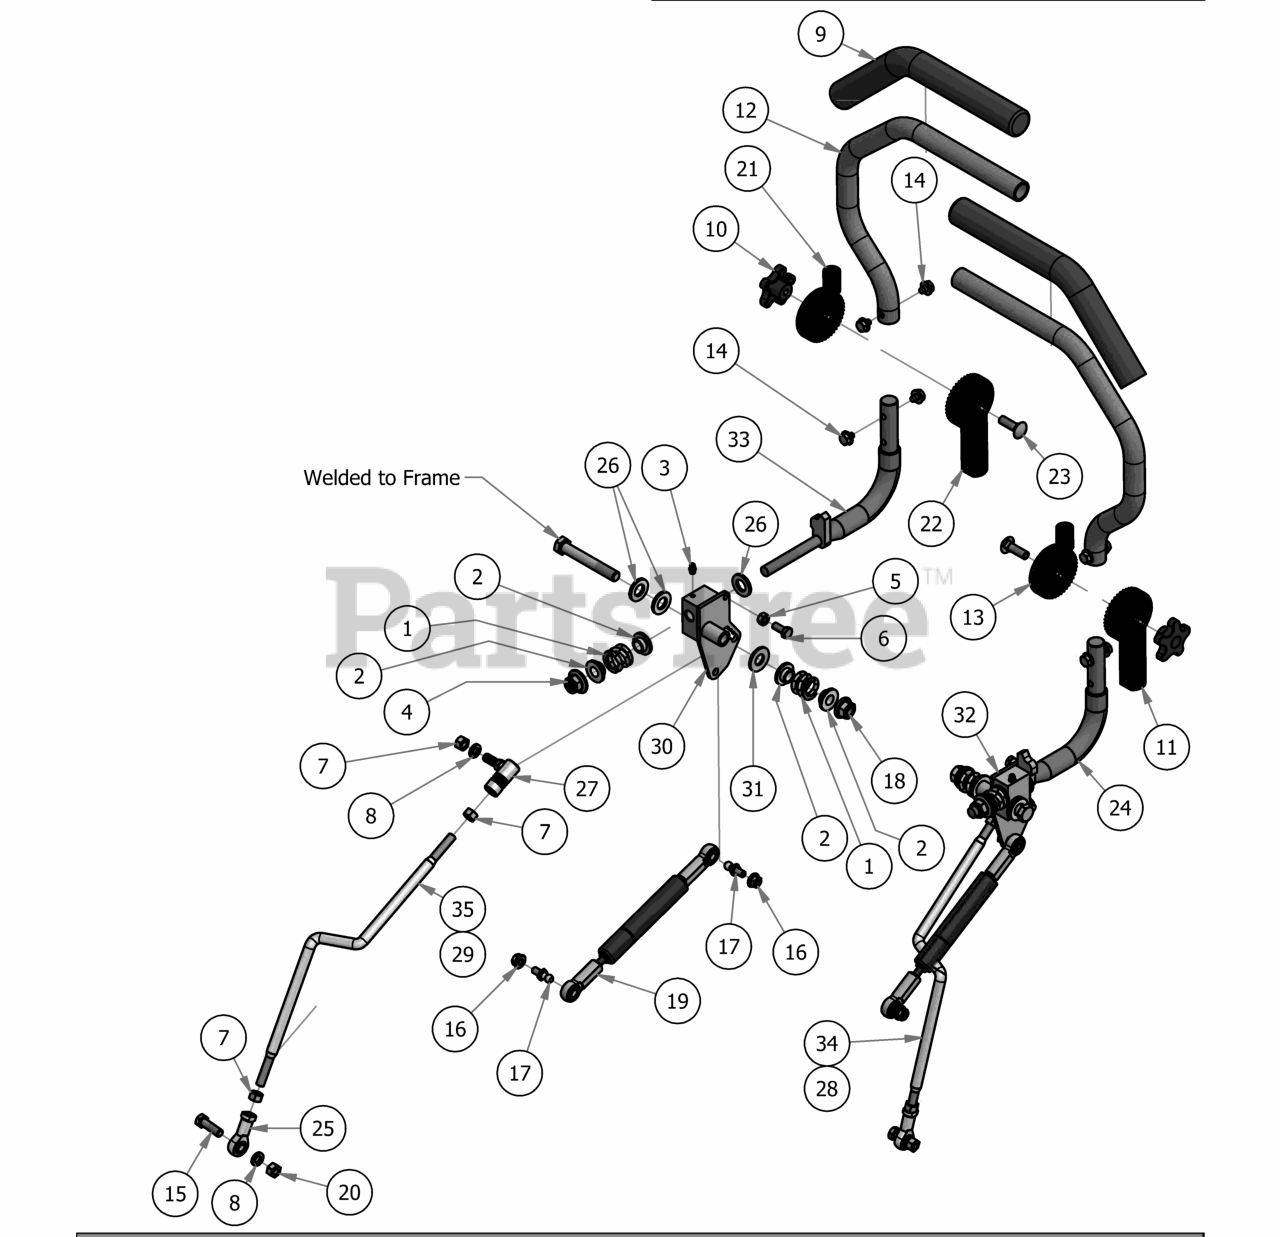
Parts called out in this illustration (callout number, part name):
1	Drive Lever Spring
2	.515 ID Nylon Shoulder Washer
3	1/4" Press in Grease Fitting
4	1/2-13 Nylon Flange Nut
6	5/16" x 3/4" Hex Bolt
7	3/8" Fine Threaded Jam Nut
8	3/8" Lock Washer
9	Black Steering Grip
10	Black Knob for Adjustable Steering Arm
11	Lower Adjuster - Steering Arm- Right
12	Upper Tube-Adjustable Steering
13	Upper Adjust Steering Arm- Right
14	5/16-18 1/2 HWH Bolt-Steering
15	3/8" x 1 1/4" Hex Bolt
16	5/16" Flange Nut
17	10mm Damper Ball Stud-Steering
18	1/2-13 Hex Flange (GR.G) ZC
19	Steering Damper
20	3/8-16 Hex Nuts Zinc
21	Upper adjuster-Steering Arm- Left
22	Lower Adjuster - Steering Arm- Left
23	3/8" x 1 1/4" Carriage Bolt
24	Stering Arm Elbow (Right)
25	Spherical Rod End - Outlaw
26	.630 ID Plastic Washer
27	Quick Release Ball Joint
28	Push Rod for Outlaw - Right
29	Push Rod for Outlaw - Left
30	2017 Drive Lever Housing - Left
31	1/2" Washer (Grade 8)
32	2017 Drive Lever Housing - Right
33	Stering Arm Elbow (Left)
34	2015 Base Outlaw Push Rod - Right
35	2015 Base Outlaw Push Rod - Left
